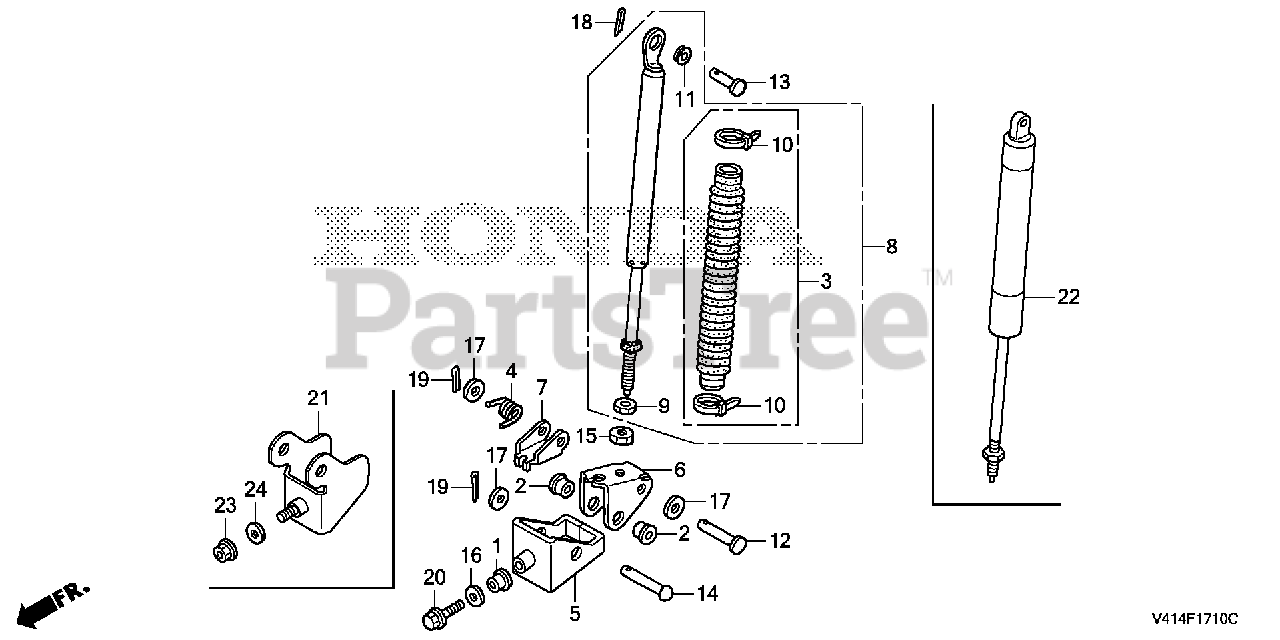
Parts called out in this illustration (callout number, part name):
4	SPRING, HEIGHT ADJUSTING
6	BRACKET, FREE LOCK
7	ARM, PUSH ROD
12	PIN (10X37)
13	PIN (7.2X20)
14	PIN (10X47)
17	WASHER, PLAIN (10MM)
18	PIN, SPLIT (2.0X15)
19	PIN, SPLIT (2.5X18)
21	BRACKET, ROLLING
22	LOCK, HEIGHT ADJUSTING FREE
23	NUT, FLANGE (M8X1.25) (SELF-LOCK)
24	WASHER, PLAIN (8MM)
